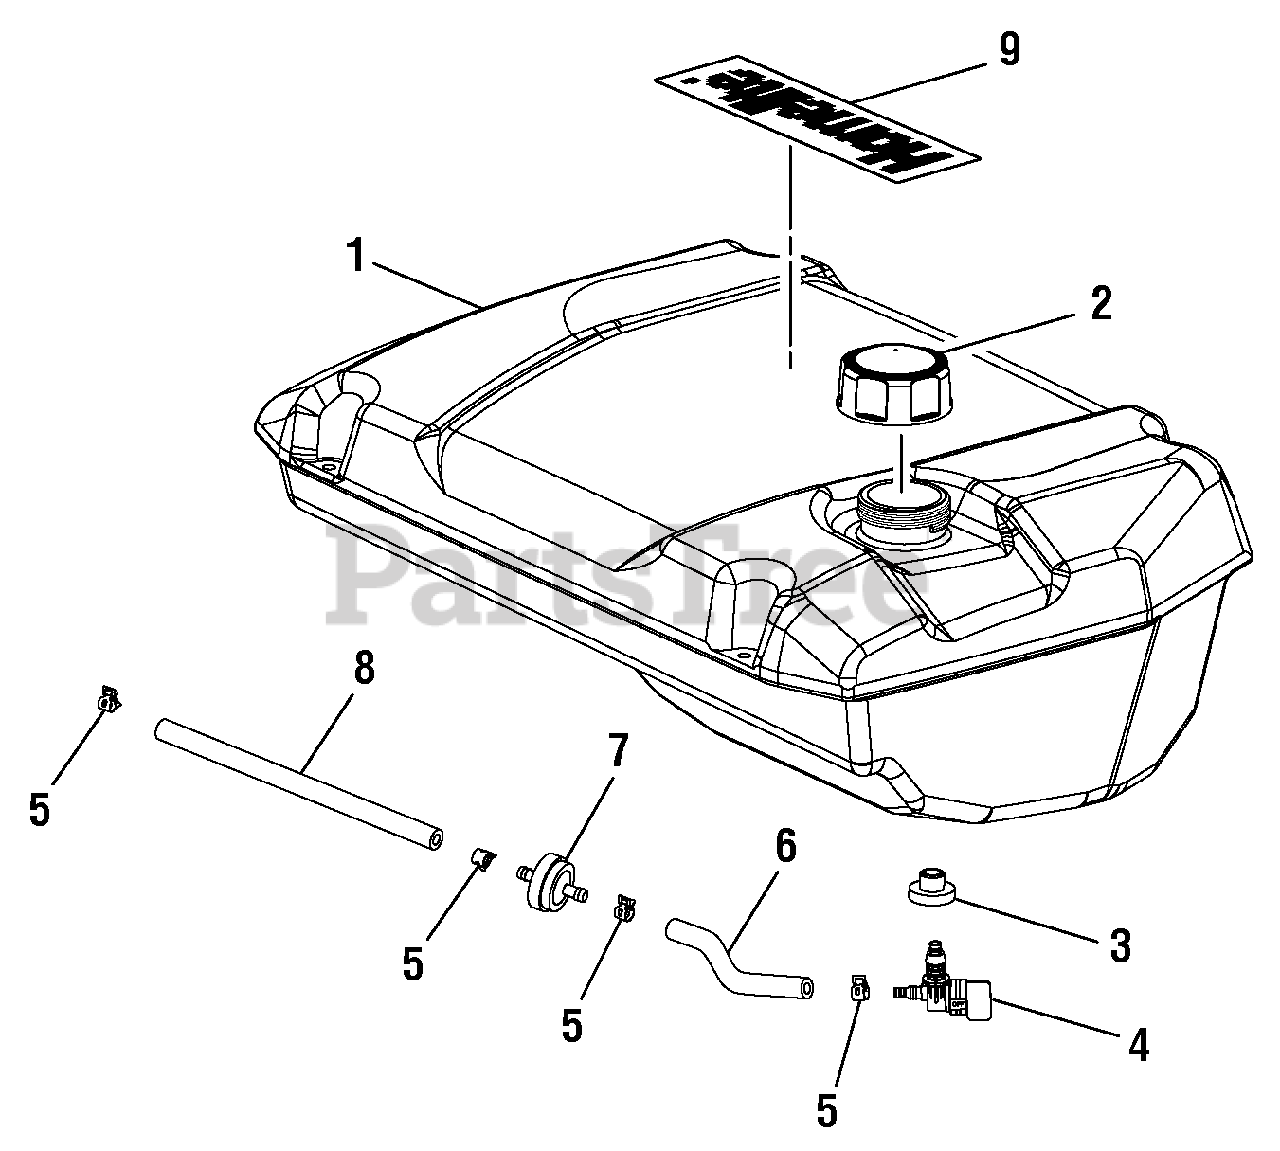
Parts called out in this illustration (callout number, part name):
1	Fuel Tank
2	Fuel Tank Cap
3	Fuel Line Clamp (1/2 in.)
4	Fuel Shut Off Valve
5	Fuel Line (6.4 mm x 105 mm)
6	Fuel Filter
7	Fuel Line (6.4 mm x 208 mm)
8	Fuel Tank Bushing
9	Fuel Tank Label
